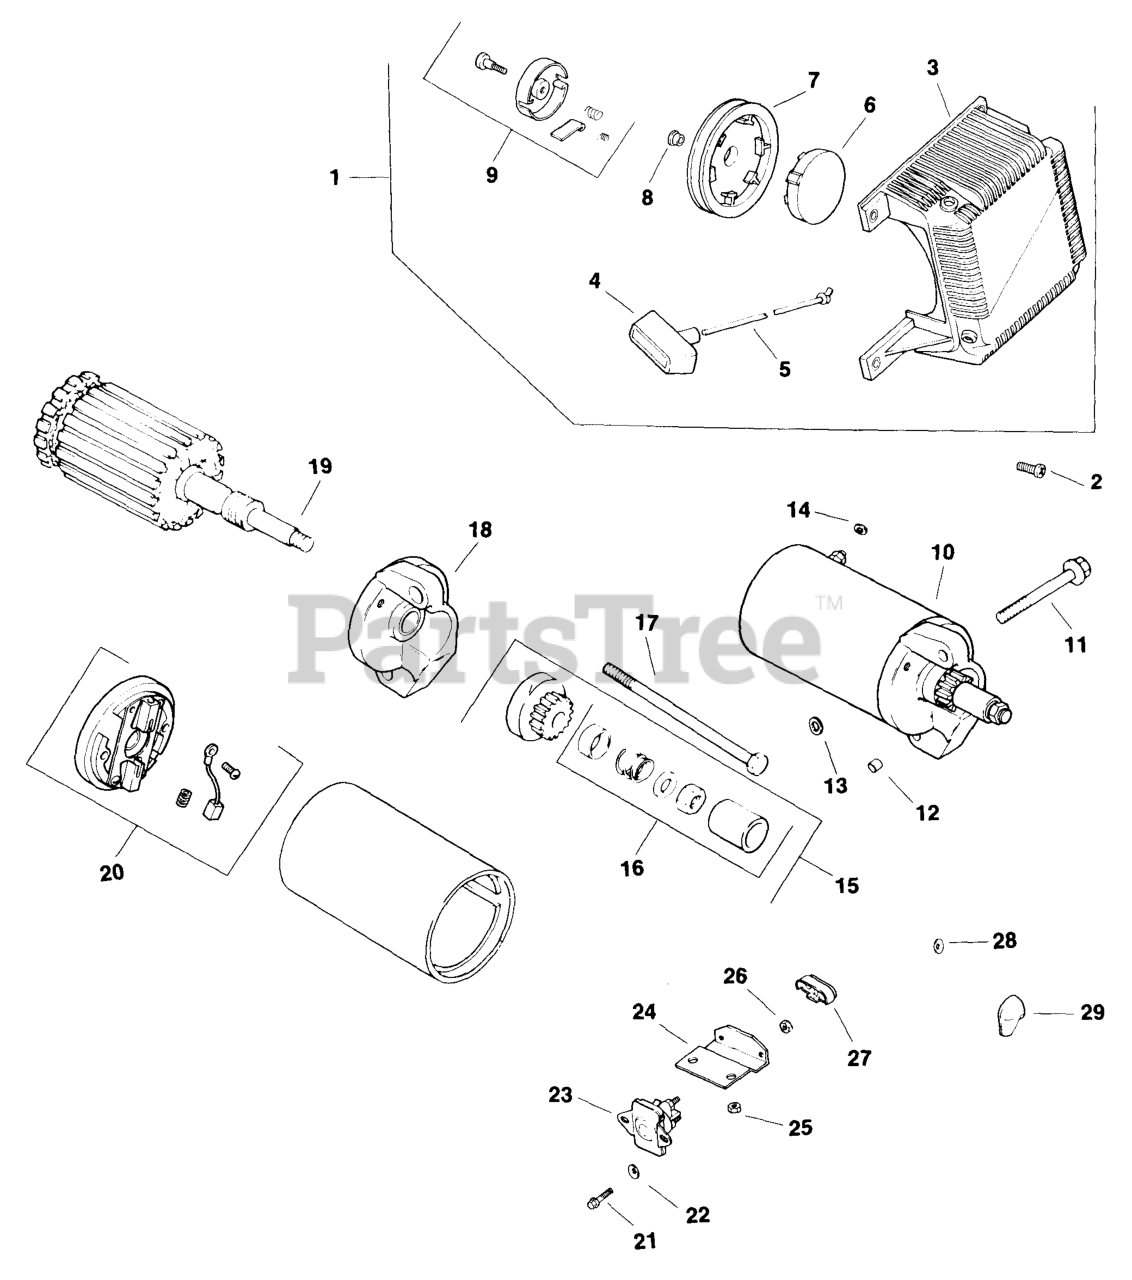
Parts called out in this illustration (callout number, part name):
1	STARTER - DISCONTINUED
2	Screw, starter mounting M6x1.0x25.5
3	HOUSING - DISCONTINUED
4	HANDLE - USE 25 166 01
5	ROPE - DISCONTINUED
6	SPRING & KEEPER - DISCONTINUED
8	SPACER - DISCONTINUED
9	KIT, DOG REPAIR - (#DSC)
